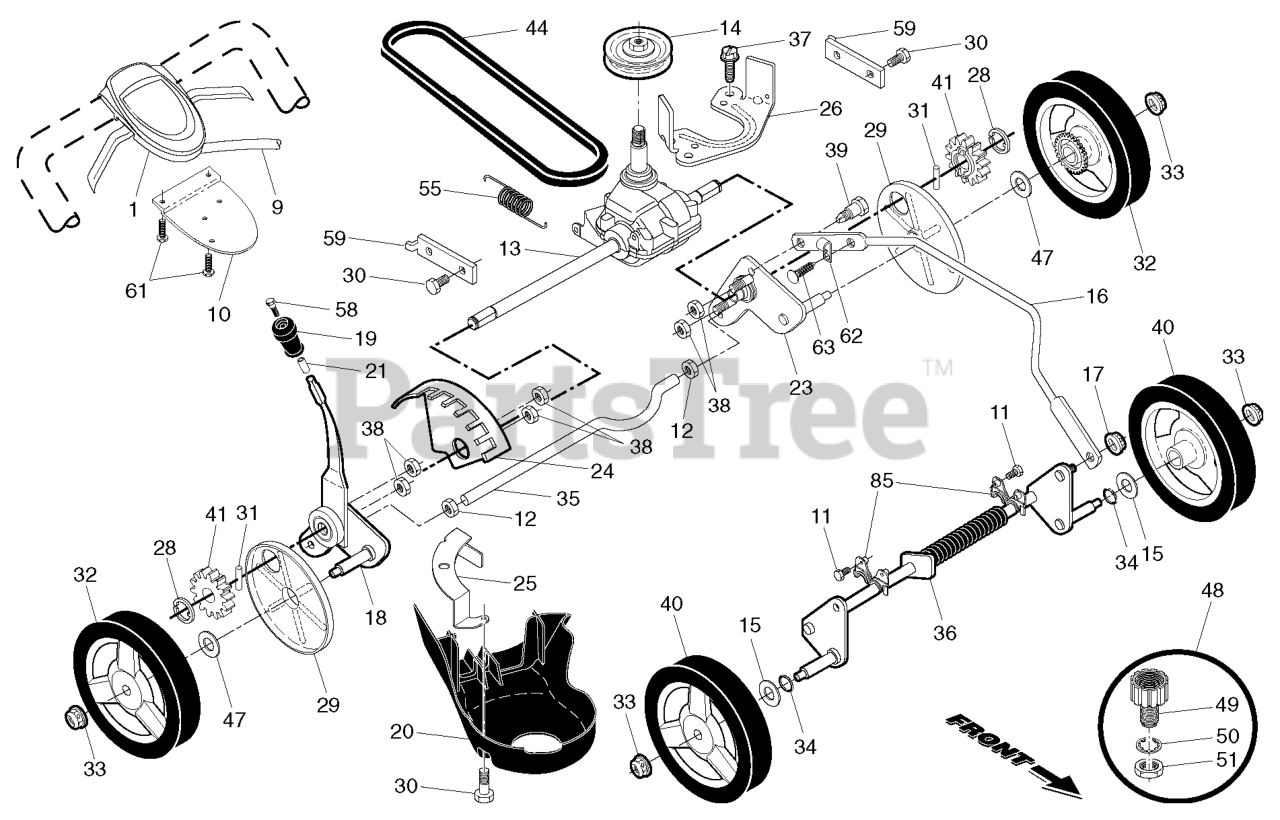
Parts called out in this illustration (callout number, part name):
1	RB CTRL.AW2.22+RGD.BS.GRY/BLK
9	CABLE.CONTROL.22RGD.GEN2
10	BRACKET.DRIVE.CONTR.GEN2.BLACK
11	SCREW.HX.13X.750
12	NUT.HEX.1/2-20
13	RP TRANSMISSION.22+.RGD.AW2/
15	WASHER.FLAT.1/2
16	ROD.CONNECTING.RGD.22+.HW.BLAC
17	NUT.LOCK.5/16-18
18	KIT.SELECTOR.ASM.437869
19	KNOB.SEL.SPRING.22+.SP.RIB.BLK
20	COVER.BELT.22.RGD
21	SCREW.PLASTIC.ANCHOR.5/16
23	ADJUSTER.ARM.ASM.AX.RT.SP.ZC
24	BRACKET.WHL.ADJ.9.POS.W/PAD
25	BRACKET.DRIVE.COVER.RGD.BZP
26	BRACKET.TRANS.BELT.KEEPER.BZP
28	E-RING 7/16 RE
29	COVER.DUST.WHEEL
30	BOLT.5/16HEX.WHS.HD
31	PAWL, DRIVE
32	KIT.WHEEL.442789X460.8"
33	NUT.HEX.FLANGE.3/8-16.LO(3 2)
34	O-RING..070X.487.NEOPRENE
35	AXLE.REAR.RGD
36	AXLE.ASM.FRONT.RGD.CLEAR.ZINC
38	NUT.HEX.FLANGE.1/4
39	SHOULDER BOLT SEMI GIMLET PT.
40	WHEEL.8IN.H3SPK.ALPHA.GRY.BB1
41	PINIION.14.TOOTH.RGD
44	BELT.DRIVE.RGD.PLUS
47	WASHER FLUT
48	KIT.WASH-OUT.PORT
49	FITTING, HOSE, WATER WASHOUT
50	WASHER.LOCK.INTERNAL.TOOTH
51	LOCKNUT.HEX.WITH.O-RING
58	SCREW.12-14X1.500
59	BRACKET.SUPPORT.22+RWGD.BZP
61	SCREW, PHILLIPS HEAD 10 X 5/8
62	CLIP.CABLE.BLK
63	FASTENER.PUSH.O.250X0.783
85	BRACKET.FRT.AXLE.SUPPORT
